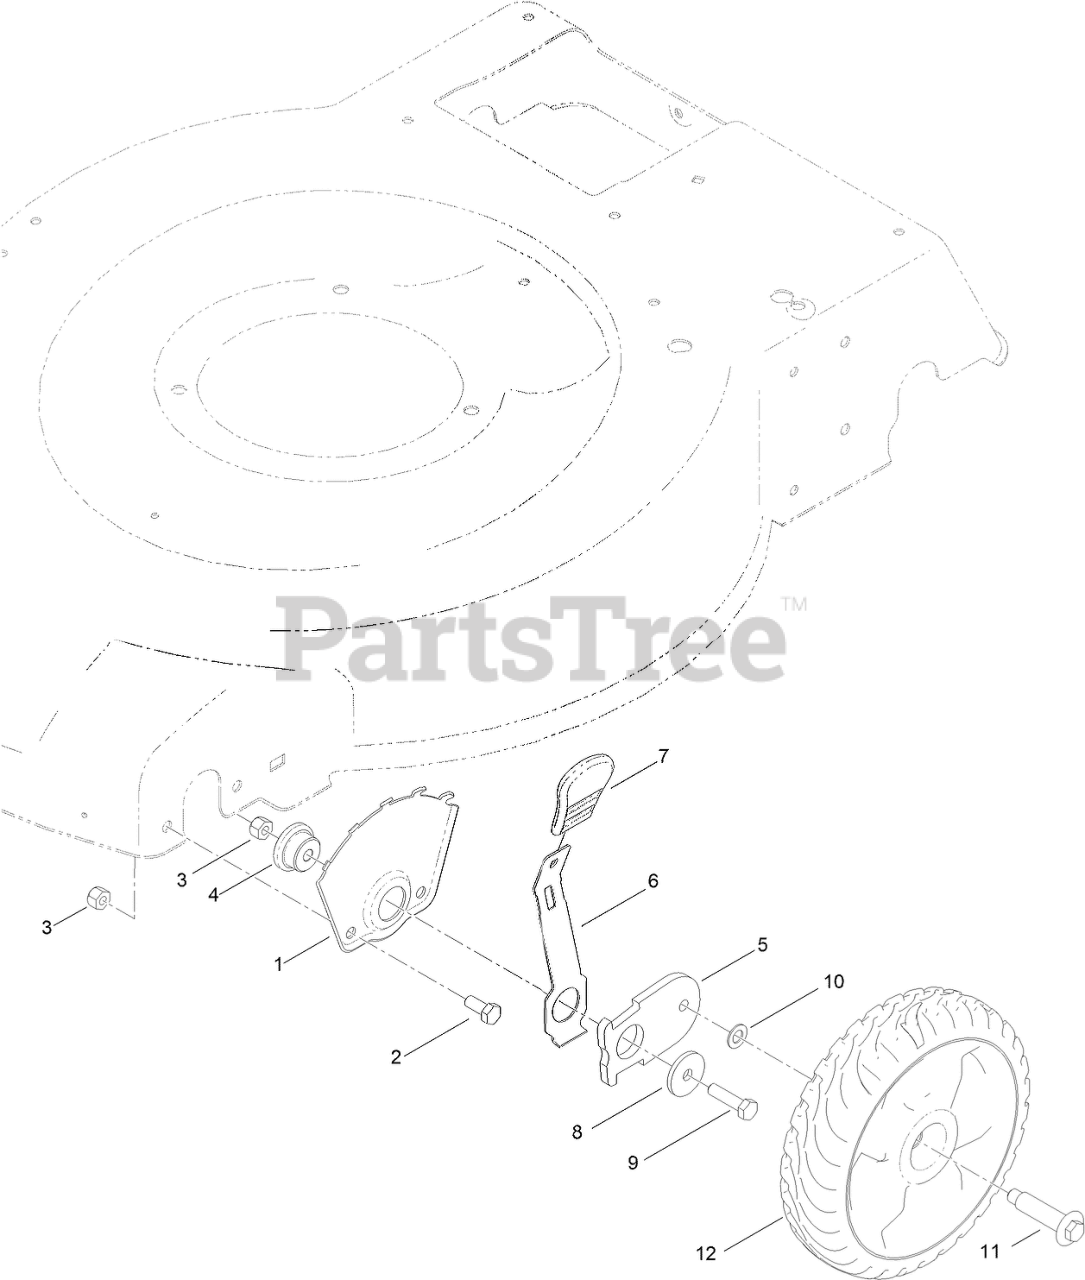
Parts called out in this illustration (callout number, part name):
1	PLATE-HOC, FRONT
2	SCREW-HH
3	NUT-LOCK, NI
4	Bushing-Mount, HOC
5	ARM-PIVOT, FRONT
6	Arm-Spring
7	KNOB-HOC
8	Washer-Flat
9	SCREW-HH
10	WASHER
11	BOLT-SHOULDER
12	8 INCH WHEEL ASM
